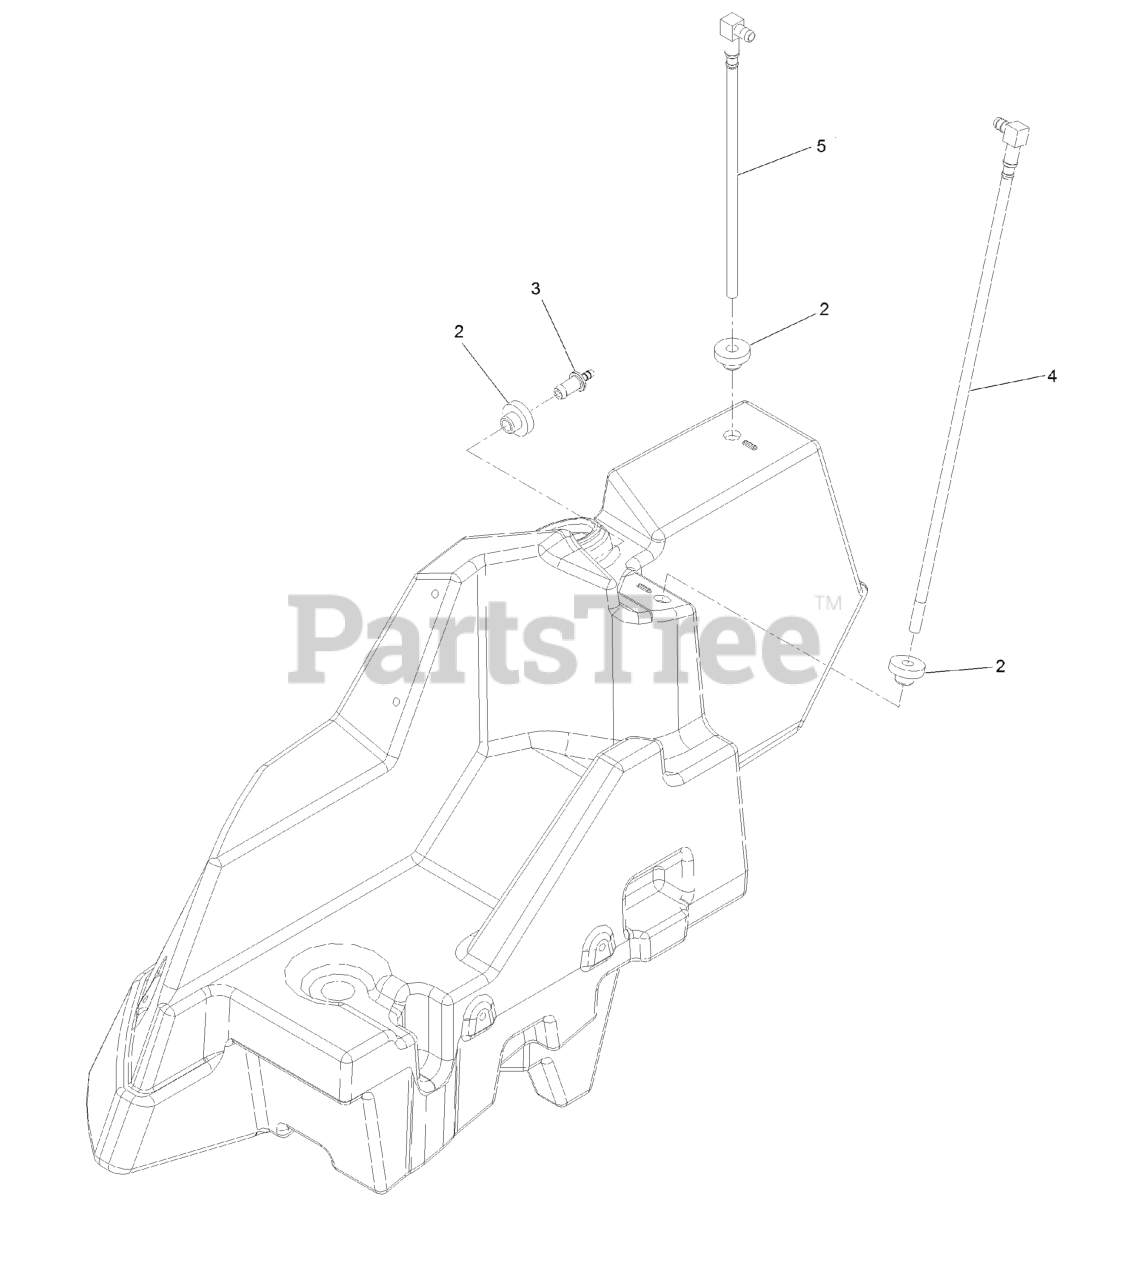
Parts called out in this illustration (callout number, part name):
2	BUSHING
3	FITTING-ORIFICE, STRAIGHT
4	PICK-UP-FUEL
5	RETURN-FUEL
